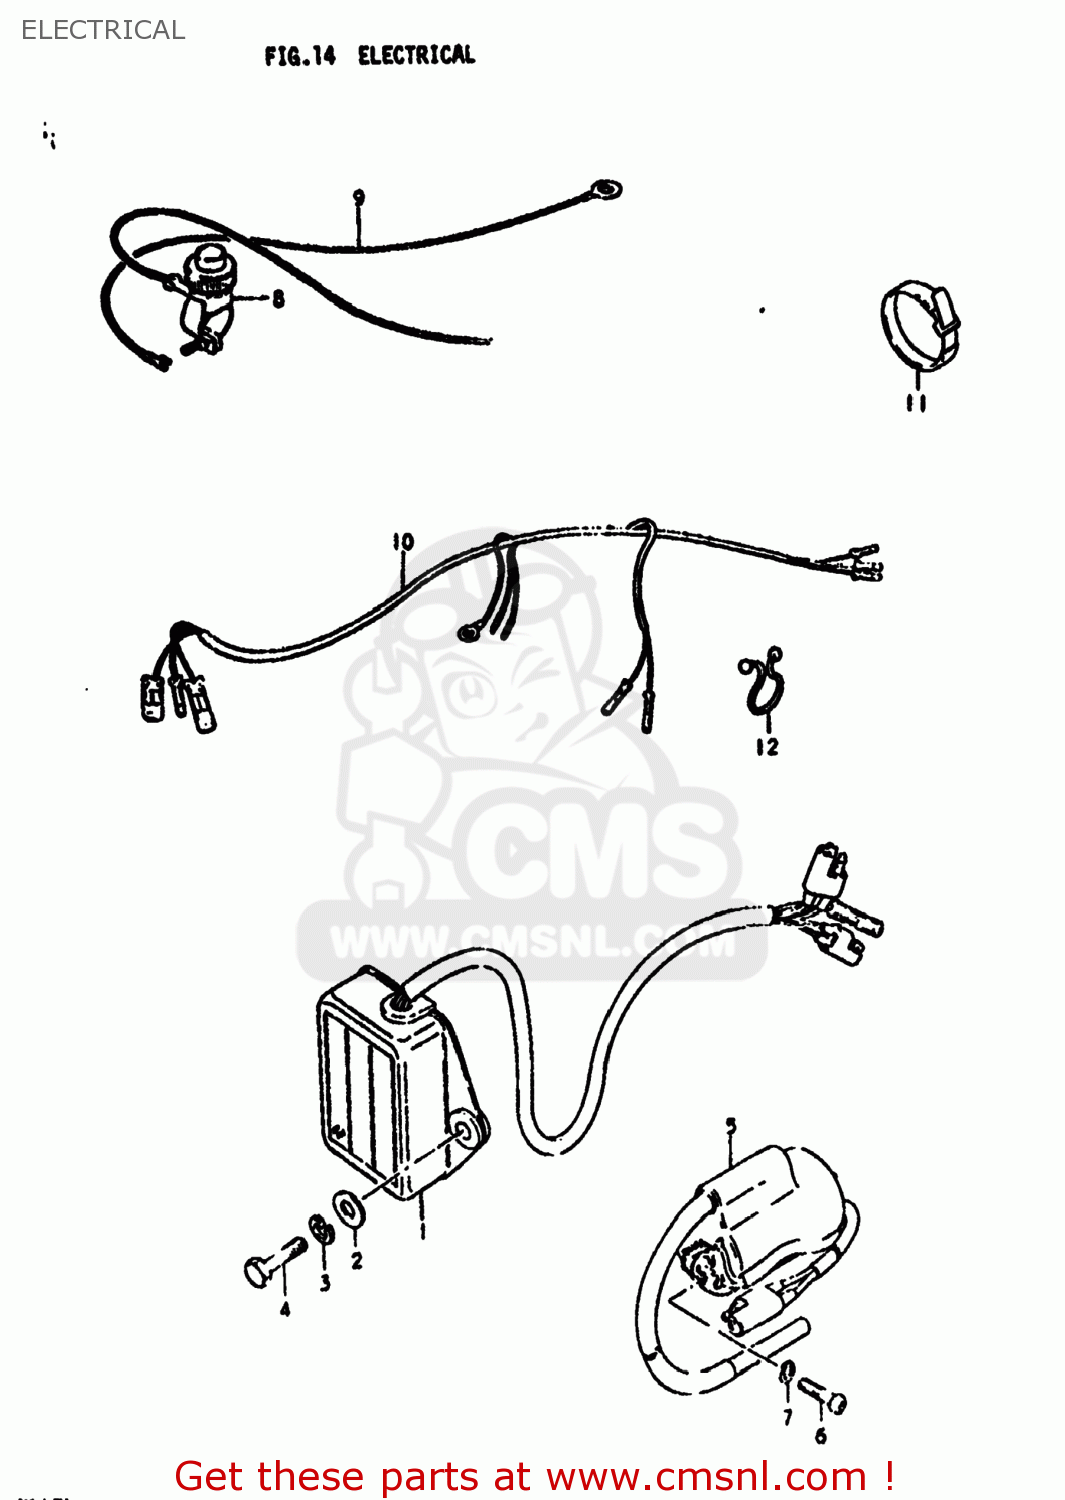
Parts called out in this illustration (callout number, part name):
1	CDI UNIT ASSEMBLY
2	WASHER(6.5X16X1.2)
3	LOCK WASHER
4	BOLT
5	COIL ASSEMBLY,IGNITION
6	SCREW 5X20
7	LOCK WASHER
8	SWITCH ASSEMBLY
9	WIRE
10	HARNESS,WIRING
11	CLAMP
12	CLIP(ID:11.5)
